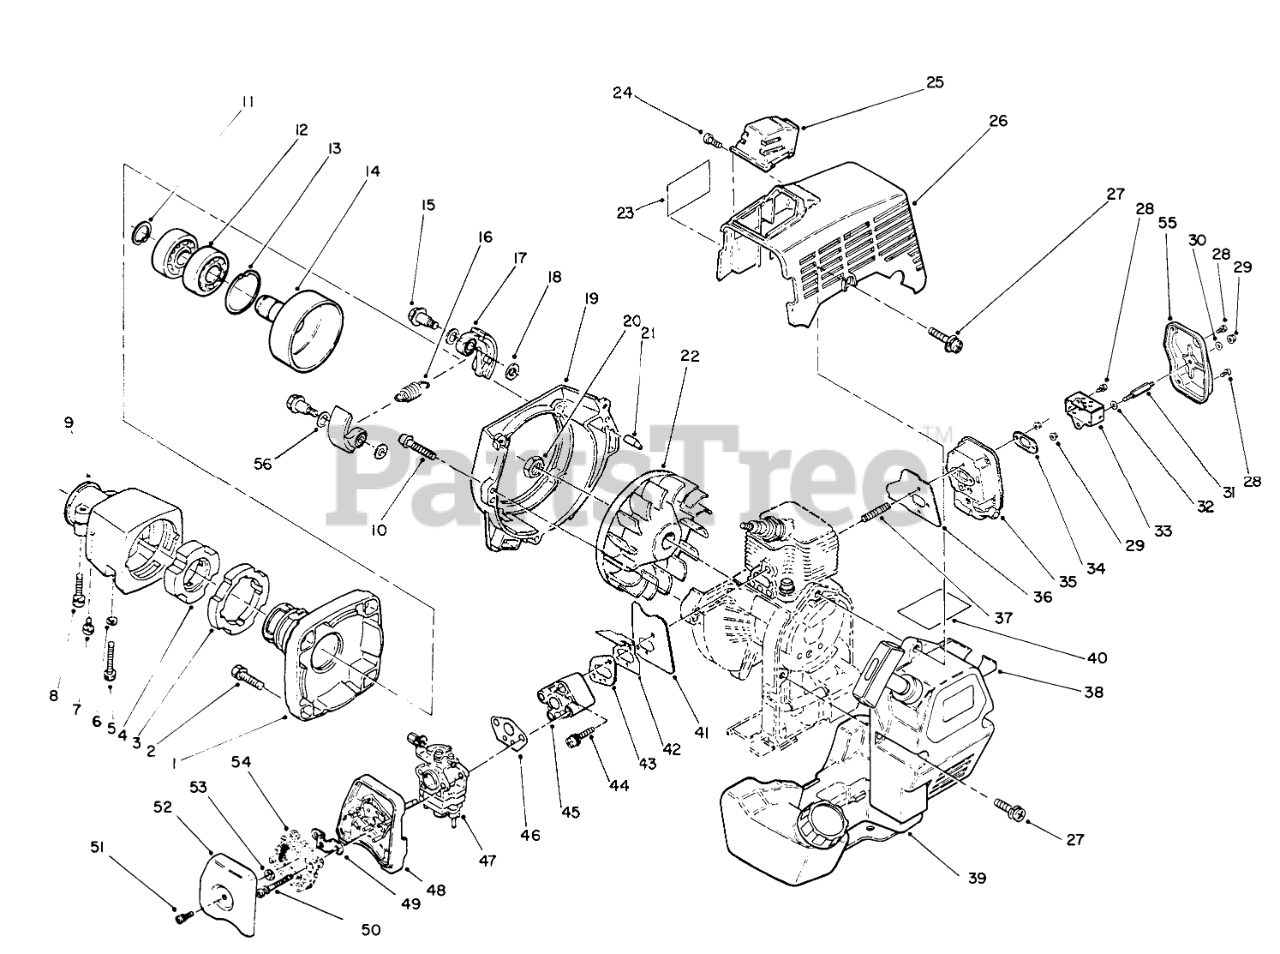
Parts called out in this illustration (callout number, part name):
1	Case-Clutch
3	RUBBER, CUSHION (A)
4	RUBBER, CUSHION (B)
6	Washer-Lock
7	Screw/Washer
8	BOLT-WASHER/ENG
9	Holder
11	SNAP RING
12	BALL BEARING
13	SNAP RING
14	DRUM, CLUTCH
15	CLUTCH BOLT
16	CLUTCH SPRING
17	CLUTCH SHOE
18	WASHER
19	FAN CASE
23	DECAL-SURFACE, HOT
24	SCREW & WASHER
25	SPARK PLUG GUARD
26	TOP COVER
27	SCREW & WASHER
28	SCREW & WASHER
29	MUFFLER FLANGE NUT
30	GASKET
31	DUAL BOLT
32	WASHER
33	Baffle
34	Plate
35	MUFFLER ASSEMBLY
36	MUFFLER GASKET
37	STUD BOLT
38	RECOIL ASSEMBLY
39	FUEL TANK ASM
40	Decal-Fuel Mix
41	INSULATOR GASKET
42	PLATE
43	INSULATOR GASKET
44	SCREW & WASHER
45	INSULATOR
46	CARBURETOR GASKET
47	CARBURETOR ASM
48	CLEANER CASE
49	BRACKET
50	SCREW W/ WASHER
51	SCREW & WASHERE
52	CLEANER COVER
54	CLEANER ELEMENT
55	Cover-Muffler
56	Washer-Wave
